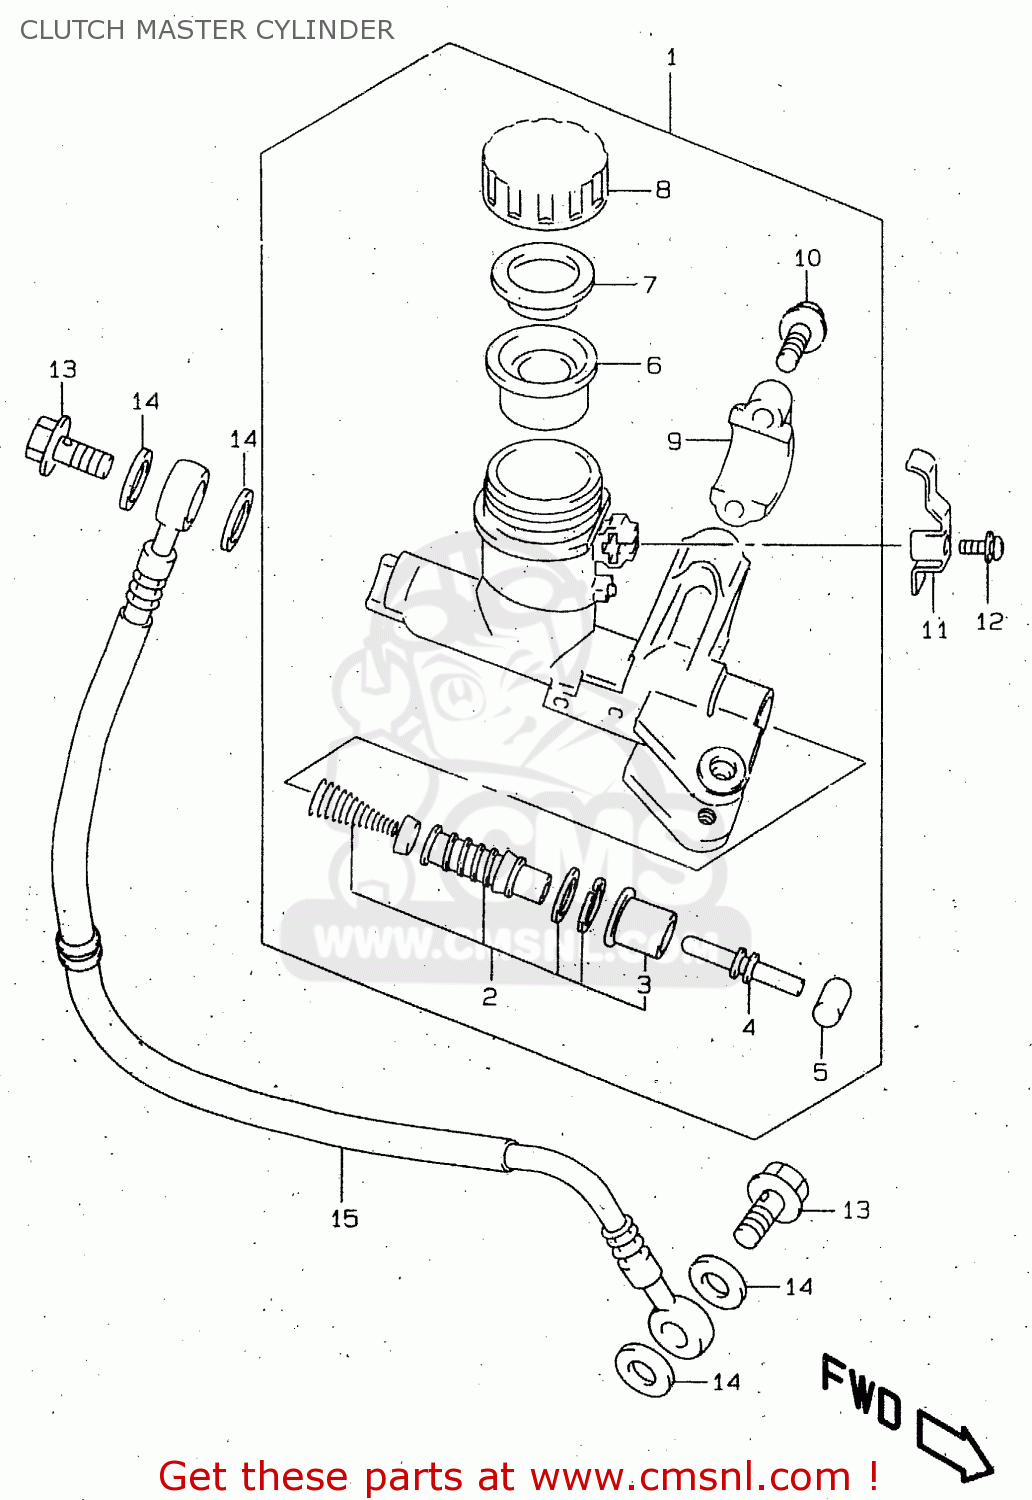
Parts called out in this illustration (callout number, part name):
1	CYLINDER ASSEMBLY,CLUTCH MASTER
2	PISTON & CUP SET
3	BOOT
4	PUSH ROD
5	BUSH
6	DIAPHRAGM
7	PLATE
8	CAP
9	HOLDER
10	BOLT(6X22)
11	PLATE,RESERVOIR TANK CAP
12	SCREW
13	BOLT UNION
14	WASHER(10X15X1.5)
15	HOSE,CLUTCH
